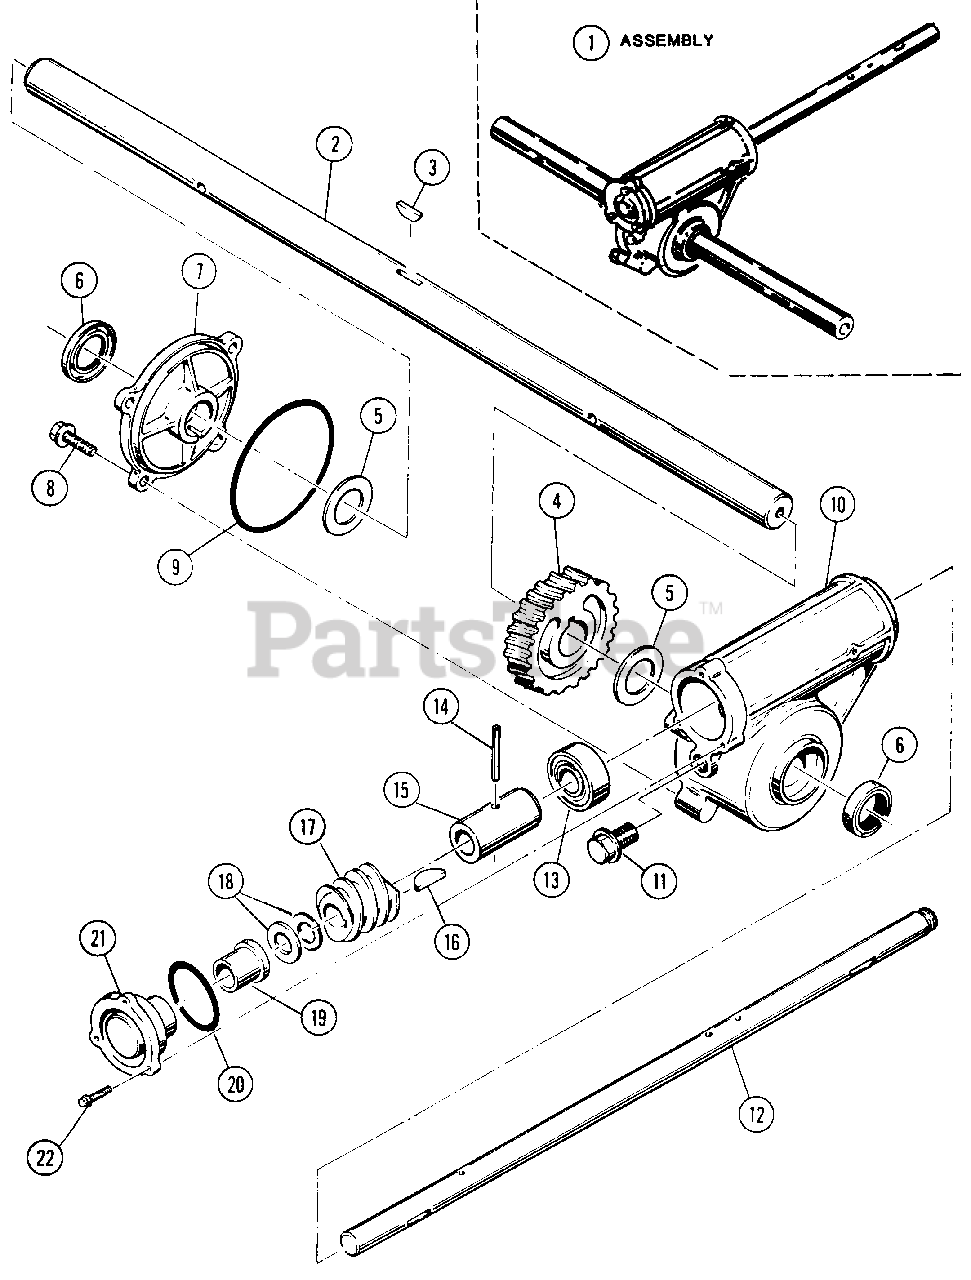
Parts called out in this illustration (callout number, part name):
1	ASSEMBLY, Gear Case
2	SHAFT, Auger
3	KEY, Woodruff
4	GEAR, Worm
5	WASHER, Thrust
6	SEAL, Oil
7	COVER, Gear Case
8	SCREW, 1/4-20x3/4 Self Tap
9	O-RING
10	CASE, Gear
11	PLUG, Check (3/8x1/2 Self Tap Screw)
12	SHAFT, Impeller Fan
13	BEARING, Ball
14	PIN, 1/4 x 1-1/2" Roll
16	KEY, 3/16 x 7/8" Woodruff
17	GEAR, Rolled Worm
18	WASHER
19	BUSHING
20	O-RING
21	CAP, End
22	SCREW, 10-24x5/8 Self Tap
